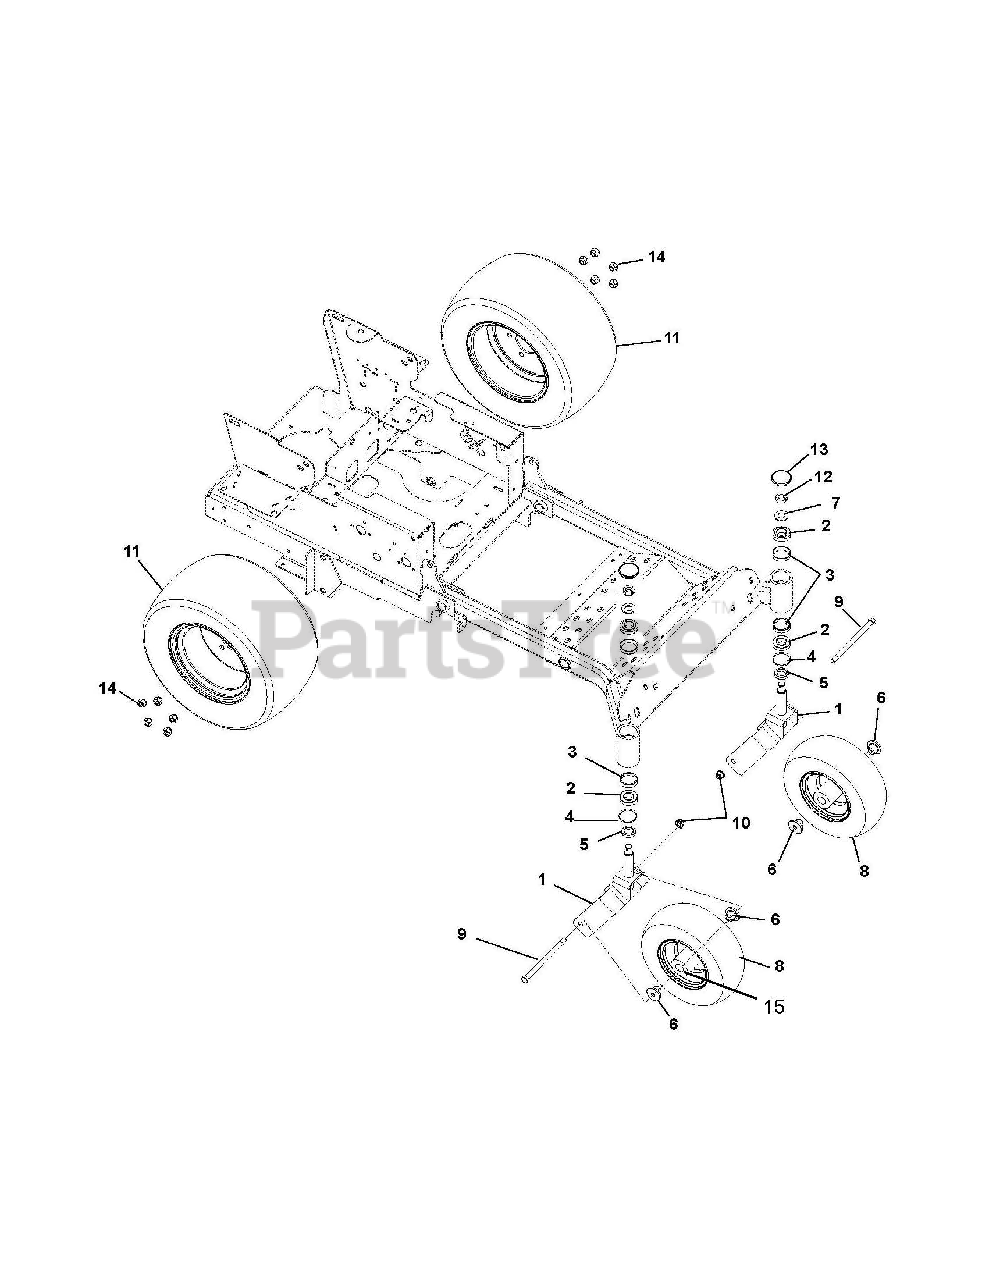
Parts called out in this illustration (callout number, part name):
1	Weldment, Front Fork
2	Bearing, Cone with Grease, 1.0 x .58
3	Bearing, Cup 1.980 x .420
4	Bearing Seal 1.5 x 2 x .18
5	Spacer, PM, 1.03 I.D. x 1.5 O.D. x .375
6	Spacer, Wheel
7	Washer, Flat, Steel .812 x 1.50 x .135
8	Tire/Wheel Assembly, 13 x 5.00-6
8	Tire 13 x 5.00-6
9	Bolt, Hex .50-13 x 7.50 Grade 5
10	Nut, Nyloc Flange .50-13
11	Tire/Wheel Assembly, 20 x 10.00-10
11	Tire, 20 x 10.00-10
12	Nut, Center Lock Jam .75-16
13	Cap, Dust
14	Wheel Nut .50-20
15	Bearing, 25MM ID x 52MM OD x 15MM
